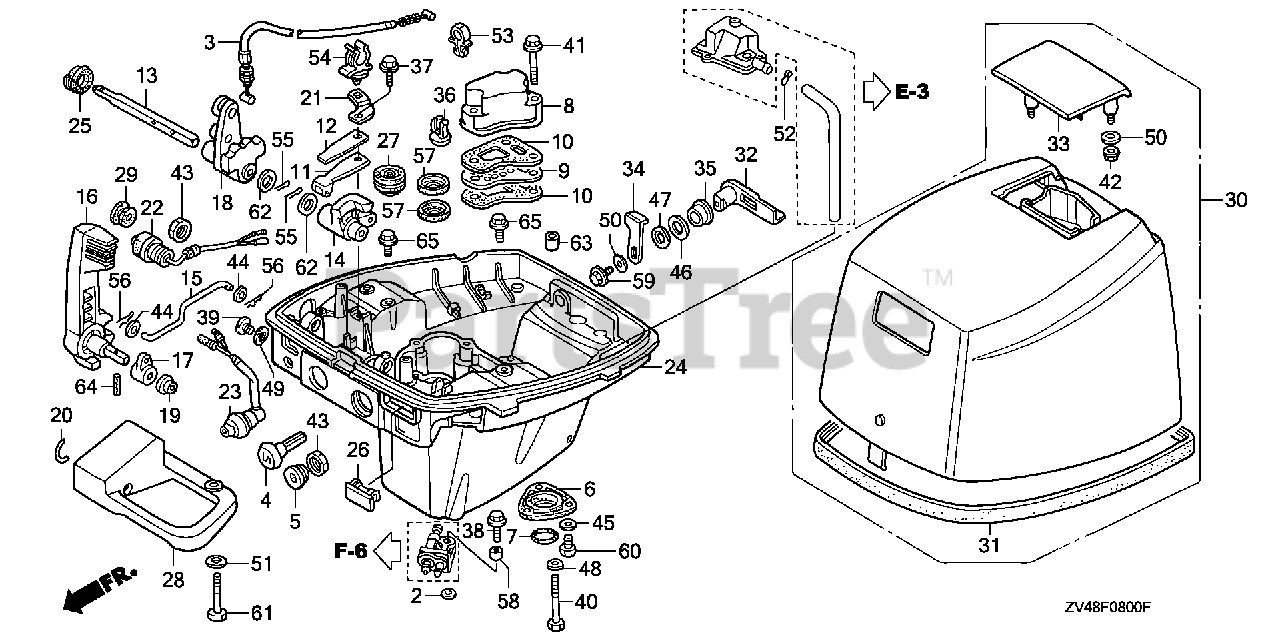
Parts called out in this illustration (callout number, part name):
2	WASHER, PIVOT
3	CABLE, NEUTRAL STARTING
4	KNOB, CHOKE
5	GUIDE, CHOKE KNOB
6	PLATE, EX.
7	BAND, EX. SEAL
8	COVER, EX. CHAMBER *NH8* (DARK GRAY)
9	PLATE, EX. CHAMBER
10	GASKET, EX. CHAMBER
11	SPRING, CLICK
12	SPRING, CLICK ASSIST
13	SHAFT, SHIFT
14	ARM, SHIFT
16	LEVER, SHIFT
17	LINK A, SHIFT
18	LINK, SHIFT (B)
19	BUSH, SHAFT
20	RUBBER, SHIFT SHAFT
21	BRACKET, WIRE HARNESS CLIP
22	SWITCH ASSY., STARTER
23	LAMP ASSY., INDICATOR
24	CASE, OIL *NH282MU* (OYSTER SILVER METALLIC-U)
25	GROMMET, OIL CASE (B)
26	GROMMET, OIL CASE (D)
27	GROMMET, OIL CASE (E)
28	HANDLE, CARRYING *NH282MU* (OYSTER SILVER METALLIC-U)
30	COVER, ENGINE *NH282MU* (OYSTER SILVER METALLIC-U)
31	SEAL, ENGINE COVER
32	LEVER, COVER LOCK *NH282MU* (OYSTER SILVER METALLIC-U)
33	HANDLE, TILT
34	HOOK, COVER LOCK
35	BUSH, COVER LOCK
36	GROMMET, WATER CHECK
37	BOLT, FLANGE (6X14)
38	BOLT, FLANGE (6X20)
39	BOLT, OIL CHECK (8X8)
40	BOLT, HEX. (6X40)
41	BOLT, FLANGE (6X35)
43	NUT, HEX. (16MM)
44	WASHER, PLAIN (5MM)
45	WASHER, PLAIN (6MM)
46	WASHER (14MM)
47	WASHER, WAVE (14MM)
48	WASHER, PLAIN (6MM)
49	WASHER, NYLON (8MM)
50	WASHER (6MM)
51	WASHER, PLAIN (8MM)
52	CLIP, TUBE (B12.5)
53	CLIP, ENGINE STOP SWITCH CORD
54	CLIP, WIRE HARNESS
55	PIN, SPLIT (2.0)
56	PIN, LOCK (5MM)
57	SEAL, WATER (14X26X6)
58	COLLAR, DISTANCE (6MM)
59	BOLT, HEX. (6X16)
60	BOLT, HEX. (6X16)
61	BOLT, HEX. (8X30)
62	WASHER, SHIFT
63	PIN, DOWEL (8X14)
64	PIN, SPRING (4X20)
65	BOLT, FLANGE (6X16)
